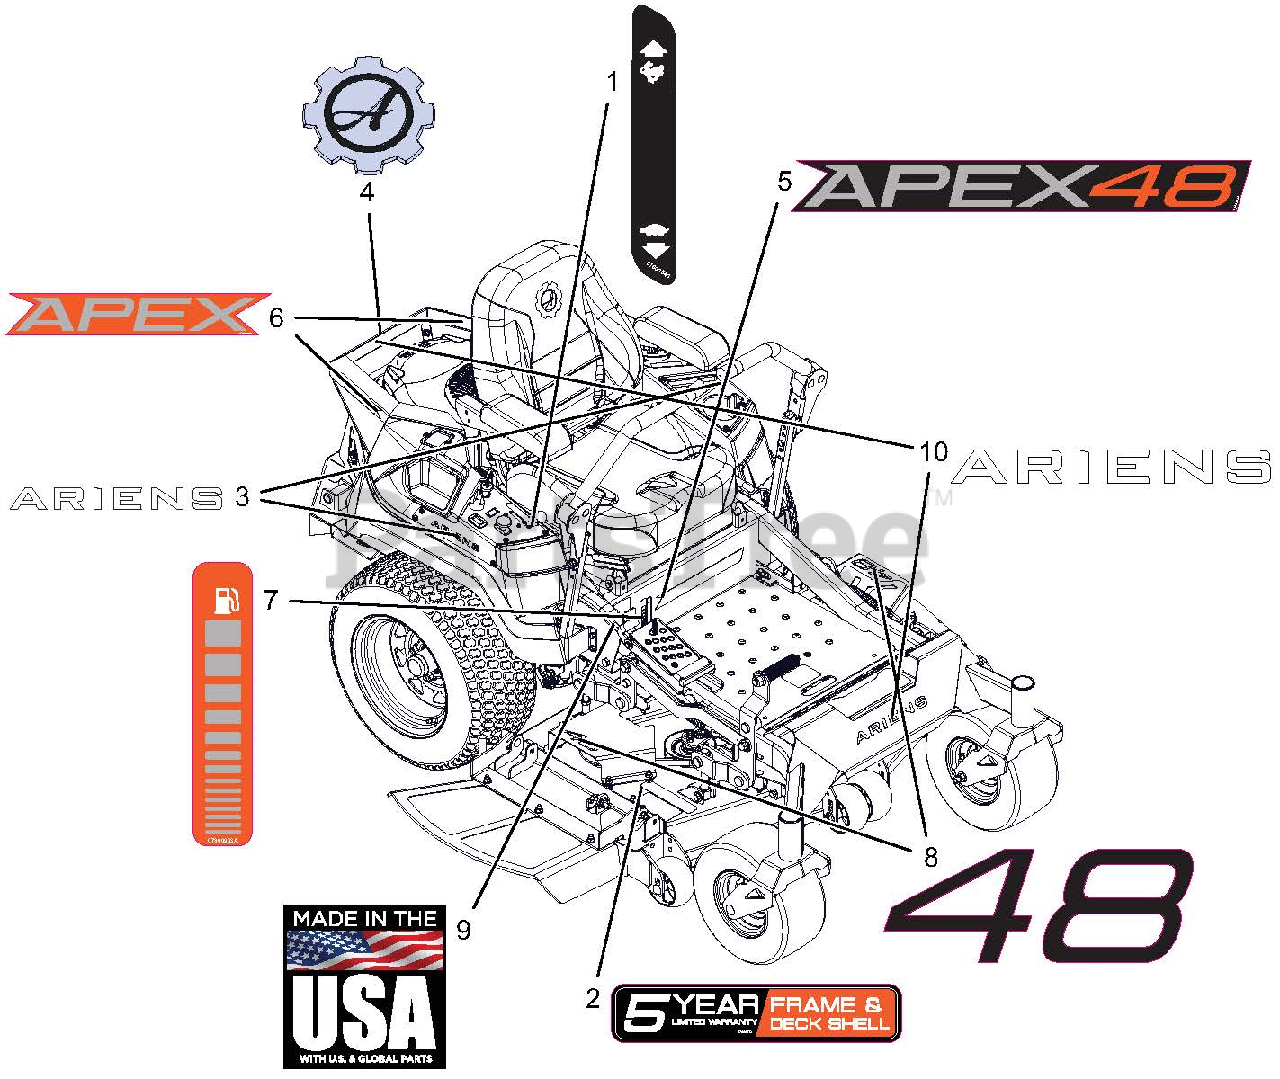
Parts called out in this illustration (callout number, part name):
1	DECAL, DASH DECAL
2	DECAL, DECK 5 YEAR-ARIENS
3	DECAL, ARIENS (6.50")
4	DECAL, ARIENS-GEAR BADGE -THK
5	DECAL, 48" APEX KICKPLATE
6	DECAL, APEX FENDER
7	DECAL, ARIENS FUEL LEVEL
8	DECAL, BLACK 48
9	DECAL, MADE IN USA
10	DECAL - ARIENS 9.625"
